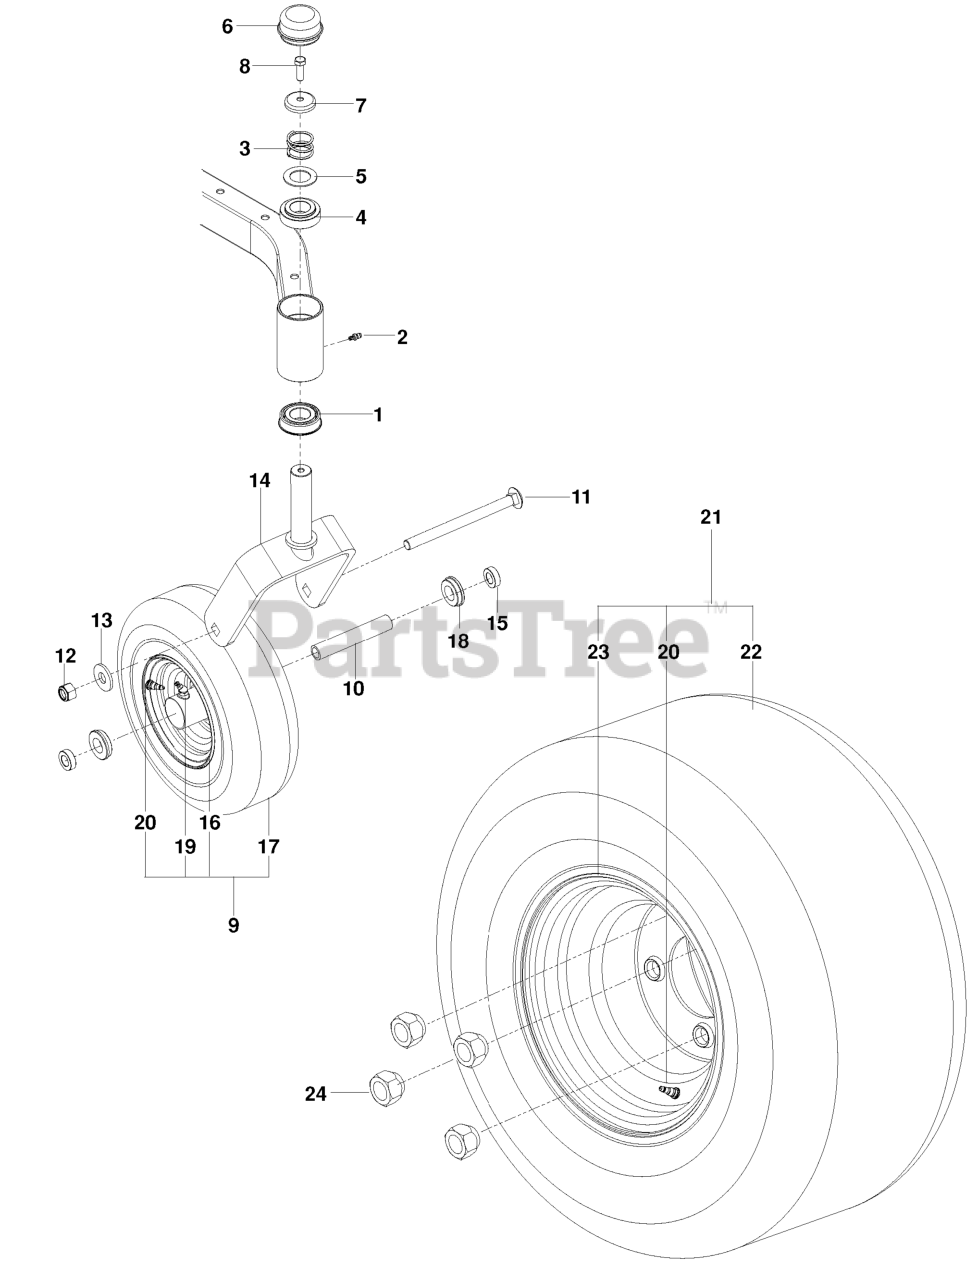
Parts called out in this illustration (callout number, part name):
1	BEARING FLANGED
2	ZERK, 3/16, DRIVE IN
3	SPRING, CASTER
4	BUSHING, CASTER
5	WASHER, 1.025 ID X 1.64
6	GREASE CAP
7	CASTER.PLUG
8	5/16-18X1 HHB G5W/NY
9	TIRE.CASTER.ASSEM.11X4-5.GR
11	RHSNB 1/2-13 X 6.50 GR2 ZD
12	NUT 1/2-13 HEX NYLOC ZD
13	WASH USS FLAT 1/2
14	YOKE.CASTER.ORANGE
15	SPACER, 5/16"
17	TIRE.11"X4"-5.4PLY.SMOOTH.KEND
18	BEARING RETAINER
19	ZERK
20	VALVE STEM TR-412
21	TIRE ASM, 20 X 8-8
22	TIRE 20 X 8, TURF
23	RIM.8X7.W/8".OFFSET.SILVER.ZTR
24	LUG NUT 1/2F
